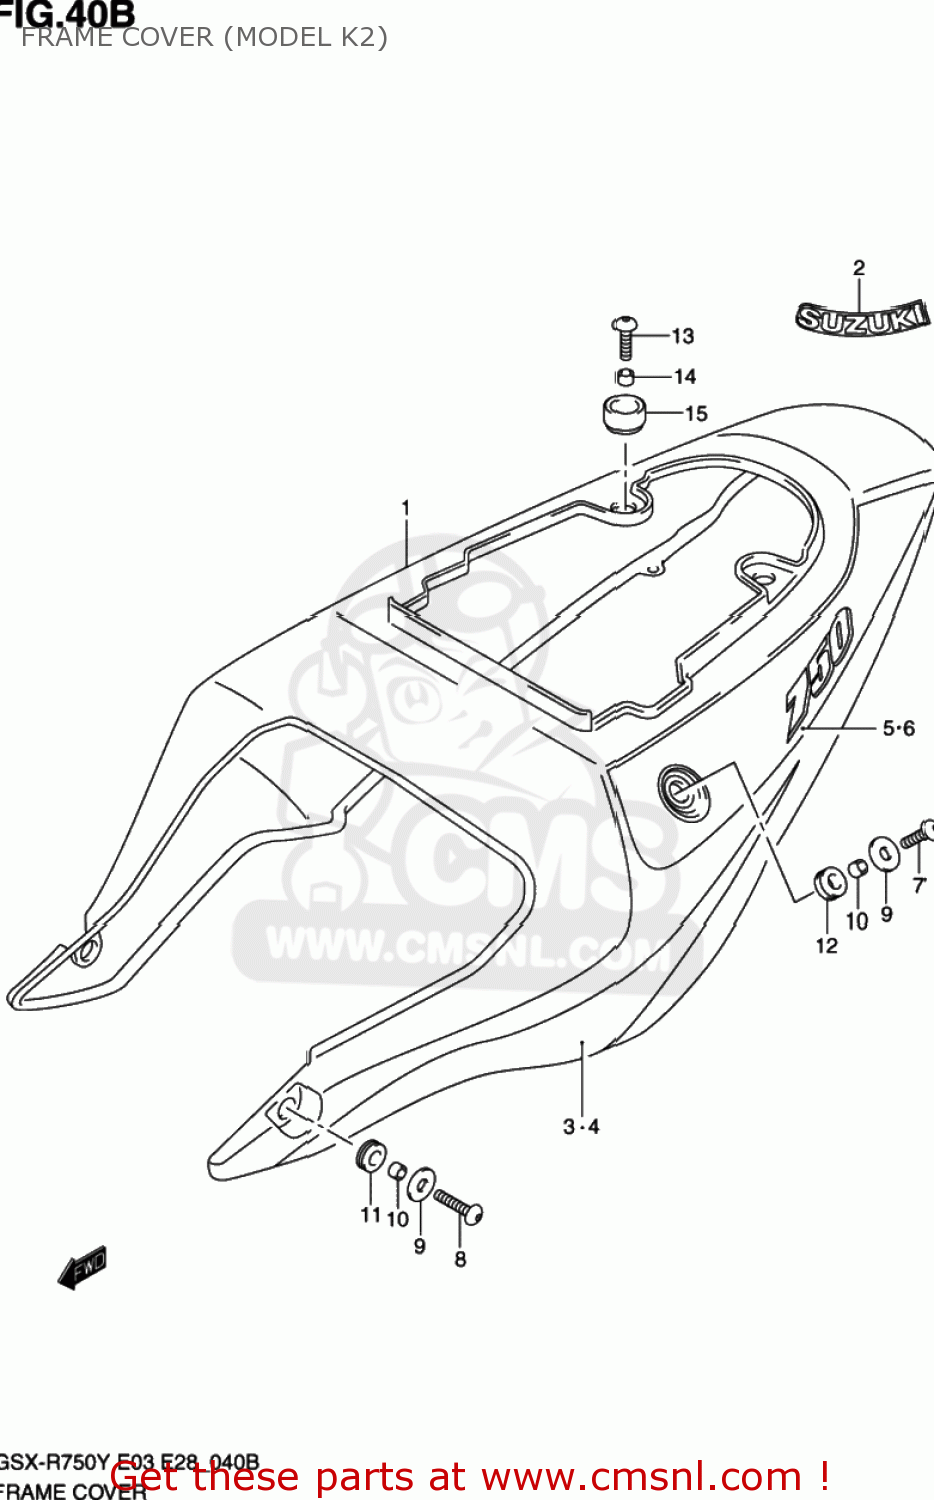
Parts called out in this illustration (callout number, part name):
1	COVER ASSY,FRAME
2	EMBLEM,SUZUKI
3	TAPE,FRAME COVER,R(BLUE)
4	TAPE,FRAME COVER,L(BLUE)
5	TAPE,FRAME COVER,R
6	TAPE,FRAME COVER,L
7	SCREW(6X25)
8	SCREW(6X30)
9	WASHER(6.5X20X2)
10	SPACER(6.5X10X7)
11	CUSHION,FRAME COVER FR
12	CUSHION,FRAME COVER SIDE
13	SCREW(6X25)
14	SPACER(6.5X10X9.4)
15	CUSHION
